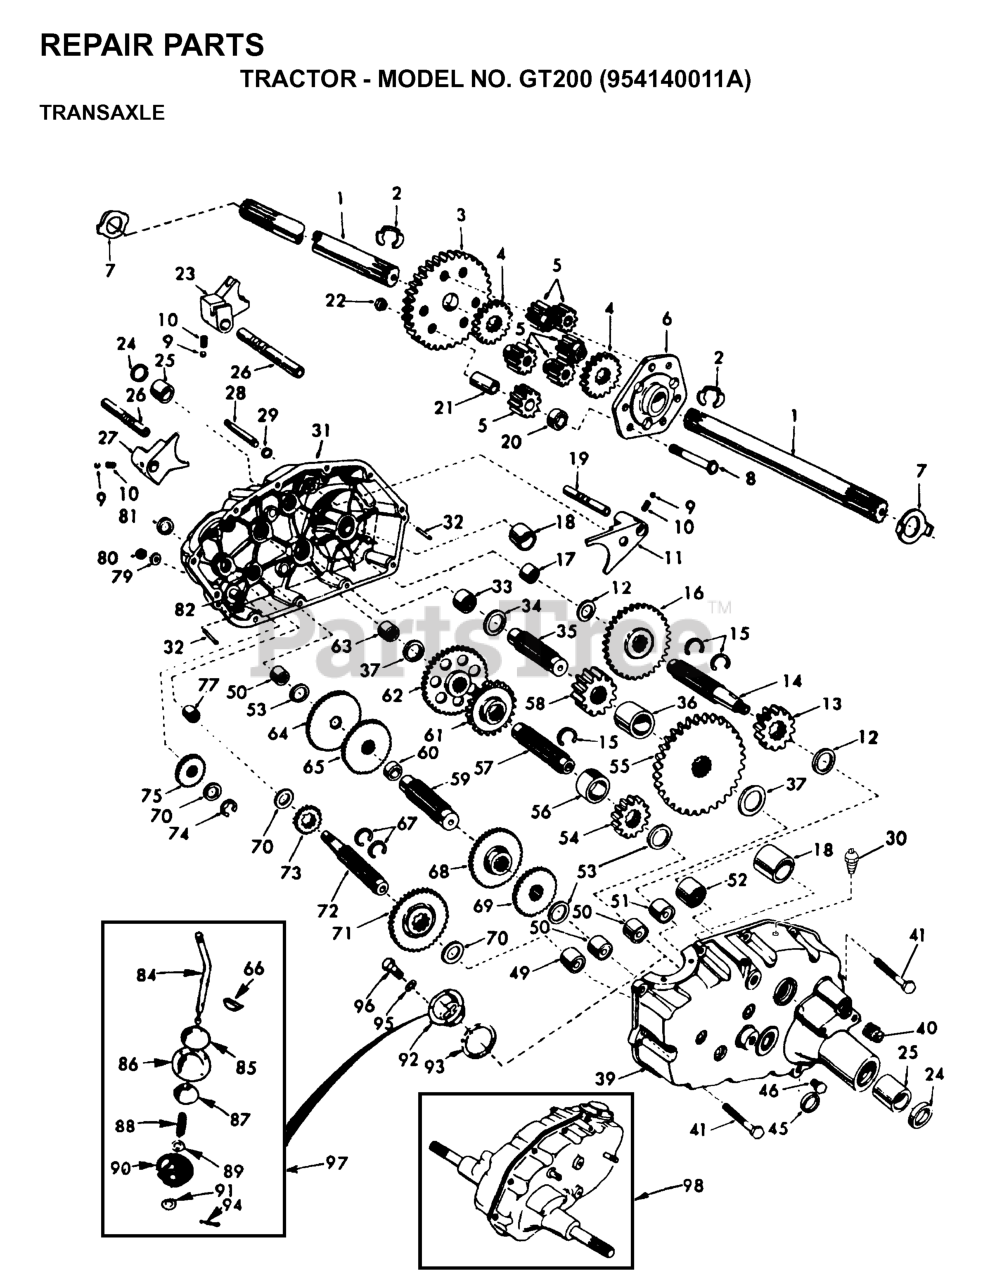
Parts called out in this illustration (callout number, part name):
1	AXLE SHAFT T
2	Ring, Klip Truarc #5304-75
3	FINAL GEAR T
4	DIFF GEAR T
5	DIFF PINION T
6	DIFF CARRIER T
7	WASHER T
8	Bolt, Hex Head 3/8-24 x 3-1/4 (1" Thread Length)
9	STEEL BALL KIT
10	SPRING
12	THRUST WASHER
13	RED PINION T
14	GEAR SHAFT
15	SNAP RING T
16	GEAR T
18	BEARING
21	PINION RS
22	GRIPCO NUT
24	OIL SEAL STD
25	BRNG. T
26	SHAFT SHIFT FORK
27	SHIFT FORK T
28	SHIFT SHAFT
29	SEAL.OIL.SHAFT.SHIFT.T
31	GEARCASE.RH.W/BEARING
33	NEEDLE BRNG T
34	WASHER RACE BEARING THRUST
35	GEAR SHAFT T
36	GEAR SPACER T
39	GEARCASE LH
40	Pipe Plug 1/2-14 N.P.T.
41	BOLT.5/16-18X1.25
49	BEARING TI
50	NEEDLE BRNG T
51	NEEDLE BRNG T
52	BEARING STD
53	BRNG RACE T
54	RED PINION T
55	RED GEAR T
56	PINION SPACER T
57	GEAR SHAFT T
58	FINAL PINION T
59	GEAR SHAFT T
61	RED PINION T
62	RED GEAR T
64	LOW SPEED GEAR T
65	GEAR.REVERSE.T
67	Snap Ring, Crescent Type
68	GEAR.SPEED.INTERMEDIATE.T/A
69	HIGH SPEED GEAR T
70	THRUST WASHER
71	CLUSTER GEAR T
72	SHAFT
73	LO SPEED PINION T
75	IDLER GEAR T
77	NEEDLE BEARING TI
80	NUT **
81	SEAL STD
82	SHAFT REVERSE IDL
84	GEAR SHIFT LVR T
86	COVER AND PIN T
87	GUIDE BALL T
90	SEAL.SHIFT
91	Washer 9/16 x 15/16 x 12 Gauge
92	GEAR SHIFT GATE T
94	COTTER PIN
95	WASHER.LOCK.HVY.HLCL.SPR.5/16
96	BOLT
97	GEAR SHFT LVR T
98	TRANSAXLE ASSY
